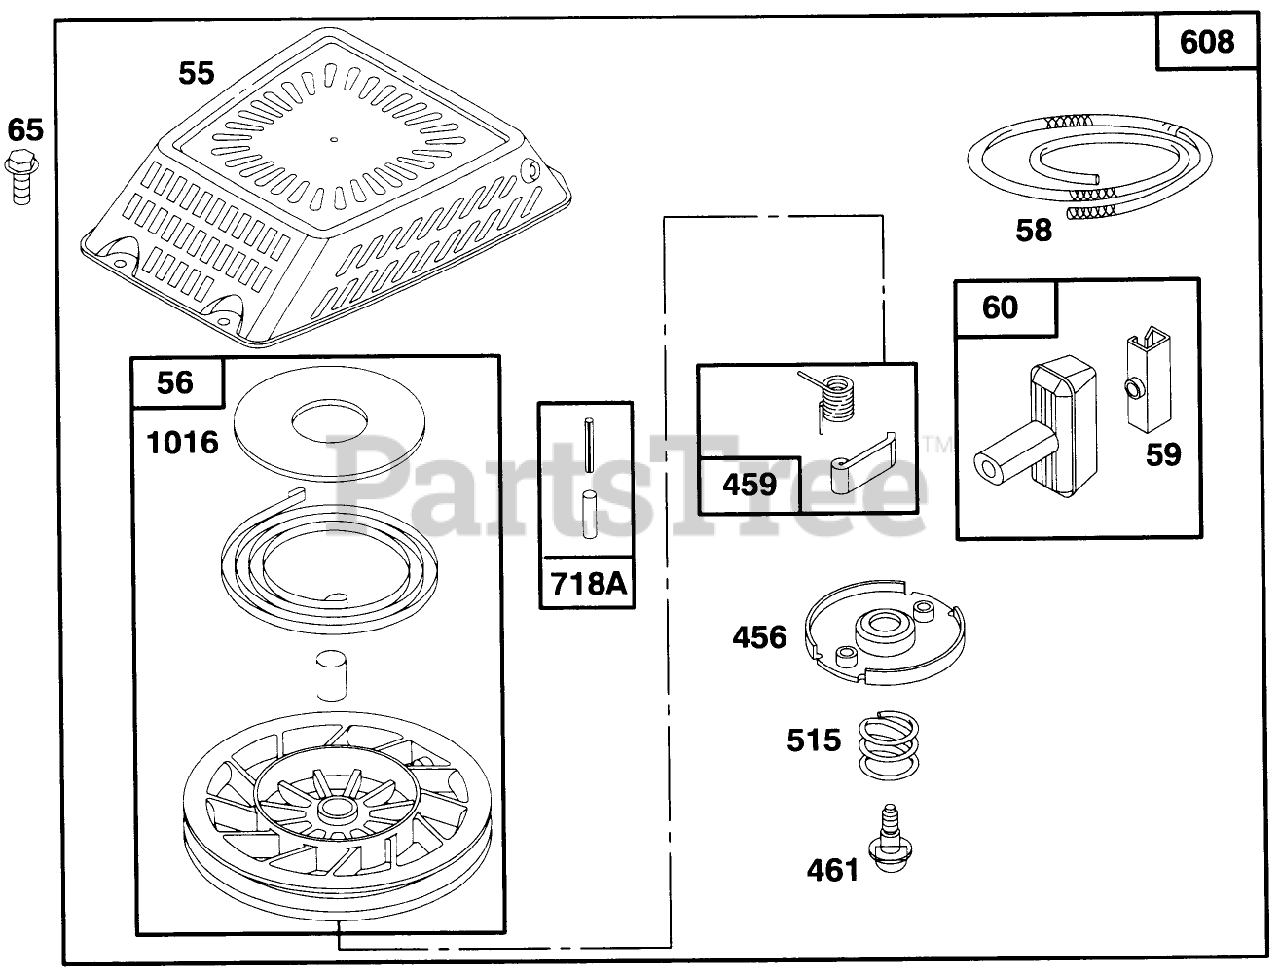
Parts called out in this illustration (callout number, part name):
59	INSERT-HANDLE, REWIND
456	RETAINER - SPRING
515	SPRING - RETAINER
